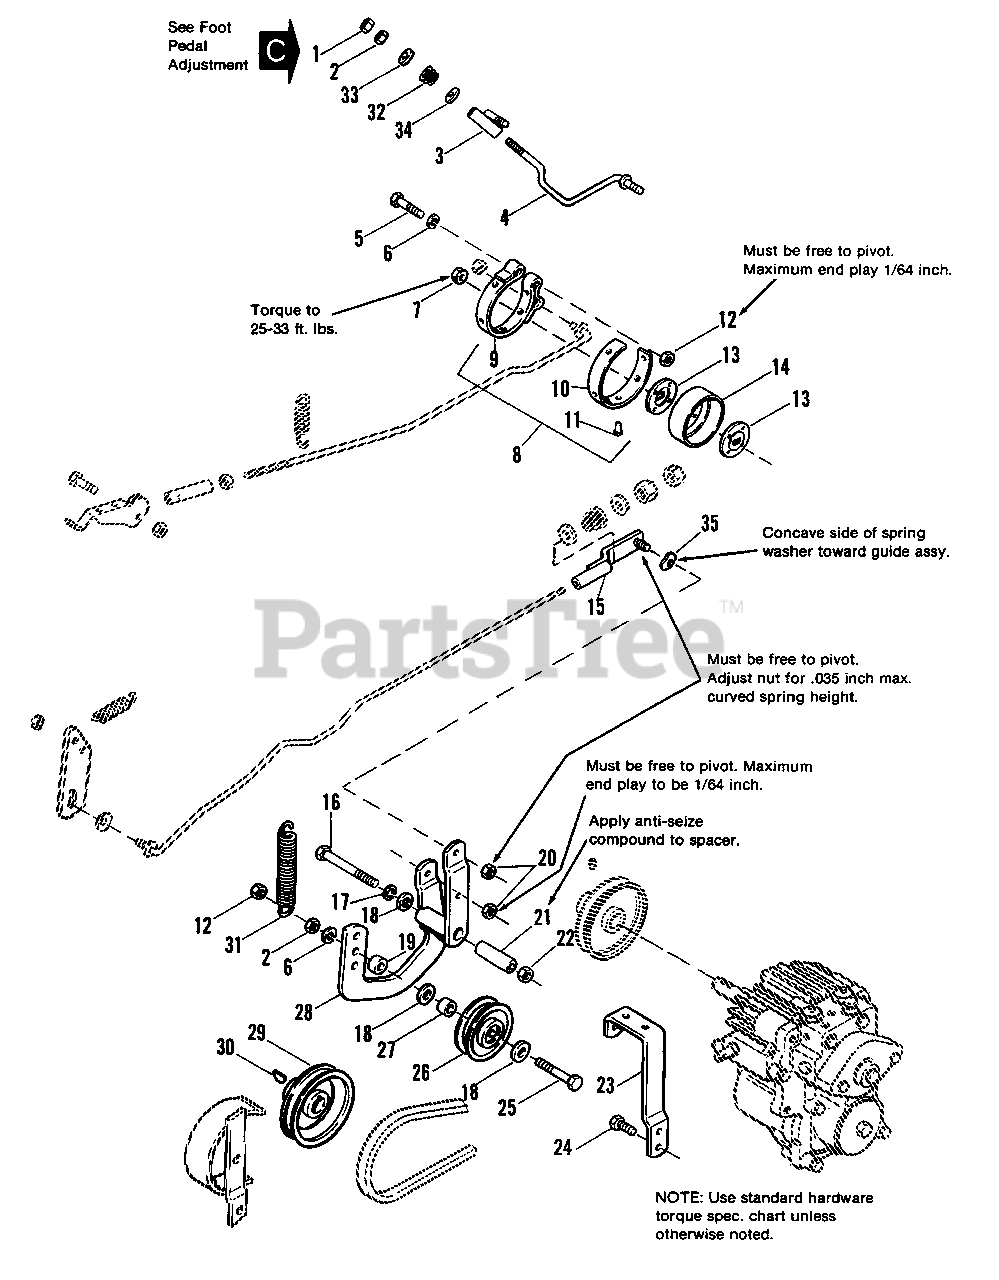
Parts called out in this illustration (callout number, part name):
1	LOCKNUT, Hex, Esna, 3/8-16
2	NUT, Hex, Full, 3/8-16
3	GUIDE ASSY., Rod
5	CAPSCREW, Hex Hd., 3/8-16 x 1-3/4
6	LOCKWASHER, 3/8
7	LOCKNUT, Hex, Flange, 7/16-14
8	BAND ASSY., Brake
9	BAND, Brake
10	LINING, Brake
11	RIVET, 3/16 x 1/4
12	LOCKNUT, Hex, 3/8-16
13	WASHER, Special
14	DRUM, Brake
15	GUIDE ASSY., Rod
16	CAPSCREW, Hex Hd., 7/16-14 x 3-3/4
17	LOCKWASHER, 7/16
18	WASHER, Plain, 3/8
20	LOCKNUT, Hex, 5/16-18
22	NUT, Hex, Full, 7/16-14
24	SCREW, Self Tapping, 3/8 x 3/4
25	CAPSCREW, Hex Hd., 3/8-16 x 2-1/2
26	PULLEY ASSY.
28	LEVER ASSY., Idler
29	PULLEY
30	KEY
32	SPRING, Cone
35	WASHER, Curved, Spring
